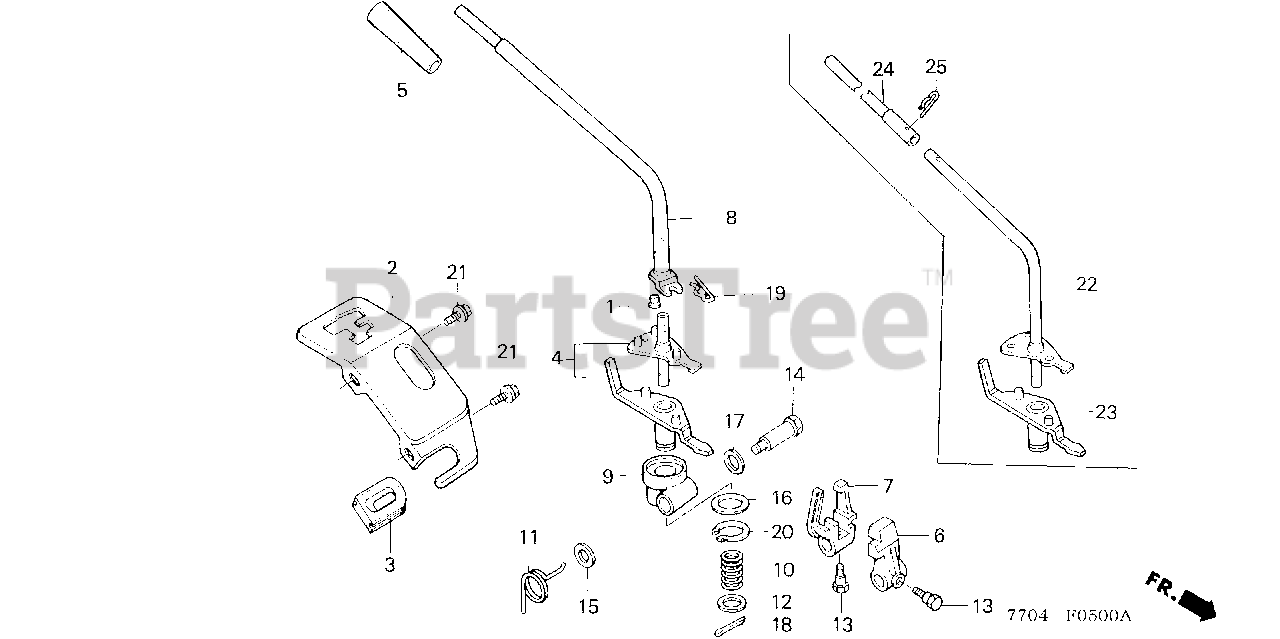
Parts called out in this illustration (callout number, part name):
2	COVER, CHANGE *NH35M* (CLOUD SILVER METALLIC)
3	GROMMET, CABLE
5	GRIP, CHANGE LEVER (ORANGE)
6	ARM A, CHANGE
7	ARM B, CHANGE
9	HOLDER, SELECT LEVER
10	SPRING, CHANGE LEVER SETTING
11	SPRING, CHANGE LEVER RETURN
12	WASHER (NOT AVAILABLE)
13	SCREW, FORK SETTING
14	BOLT, SELECT LEVER HOLDER
15	WASHER, HEAD (8MM)
16	WASHER (18.2X26X1)
17	WASHER, PLAIN (12MM)
18	PIN, SPLIT (3.0X18)
20	CIRCLIP, OUTER (18MM)
21	BOLT, FLANGE (6X10)
22	LEVER, CHANGE
23	LEVER ASSY., CHANGE
24	BAR, CHANGE
25	PIN, SPLIT (2.5X30)
